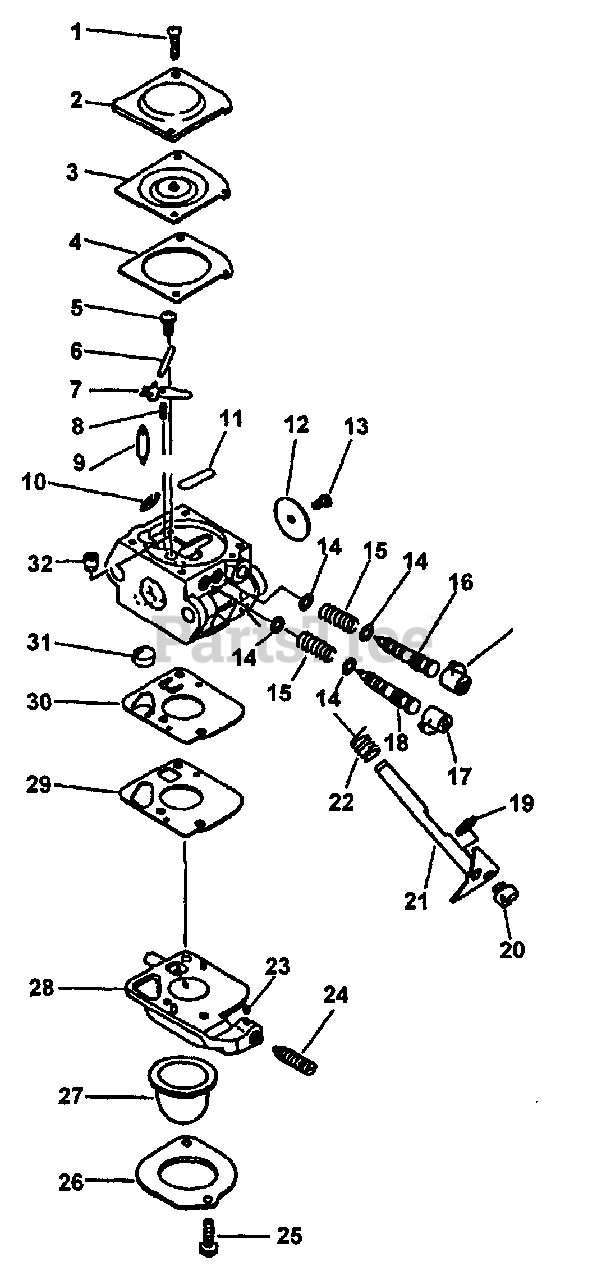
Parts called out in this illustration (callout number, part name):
2	COVER, METERING
3	DIAPHRAGM, METERING
4	GASKET, METERING
5	SCREW, METERING LEVER PIN
6	PIN, METERING LEVER
7	LEVER, METERING
8	SPRING, METERING LEVER
9	VALVE, NEEDLE
10	RING, RETAINING
11	PLUG, WELCH
12	VALVE, THROTTLE
16	NEEDLE - LOW SPEED
17	NEEDLE - HIGH SPEED
18	CAP, LIMITER
19	RING, RETAINING
21	SHAFT, THROTTLE
22	SPRING, RETURN
23	PIECE, FRICTION
24	SCREW, IDLE ADJUST
25	SCREW, RETAINER
26	RETAINER, PURGE BULB
27	BULB, PURGE
28	BASE, PURGE
29	GASKET, PURGE
30	DIAPHRAGM, PURGE
31	STRAINER
32	NOZZLE, CHECK VALVE
